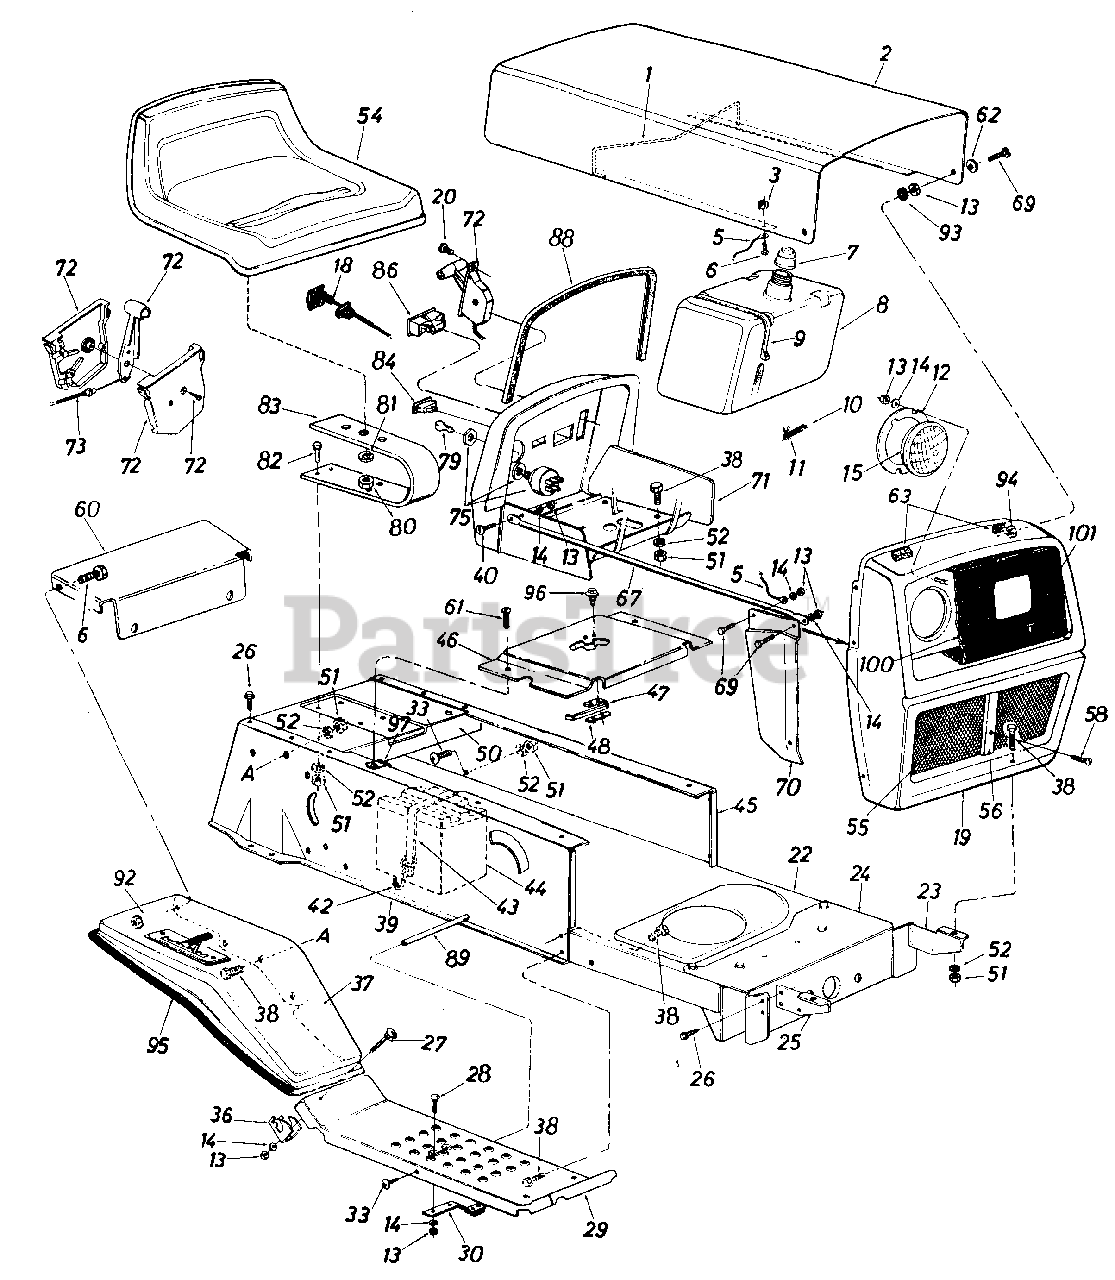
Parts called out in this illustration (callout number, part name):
3	Hex Sems Nut #10-24 Thd.
5	Hood Stop 7" Lg.
6	Truss Hd. Scr. #10-24 x 1/2"
7	Fuel Cap Gauge
8	Fuel Tank
9	Tie Strap
10	Fuel Line
12	Headlight Retainer
13	Hex Nut 1/4-20 Thd.
14	L-Wash 1/4" I.D.
15	Headlight
18	Choke Control 29" Lg.
19	Grille Ass'y.
20	Truss Mach. AB-Tap Scr. #10 x .50" Lg.
22	Lower Frame
23	Grille Mount Brkt. L.H.
24	Front Pivot Brkt.
25	Grille Mount Brkt. R.H.
26	Hex Wash. Hd. AB-Tap Scr. 5/16 x .75" Lg.
27	Carriage Bolt 1/4-20 x 2.0"*
28	Carriage Bolt 1/4-20 x .62"
29	Running Board
30	Blade Brake Ass'y.
33	Truss Mach. Scr. 5/16-18 x .75" Lg.
36	Fender Clamp
37	Fender
39	R.H. Side Frame
40	Hex Bolt 1/4-20 x .62" Lg.
42	Battery Strap Hook
43	Battery Hold Down Strap
44	12-V Battery
45	L.H. Side Frame
46	Shift Cover
47	Reverse Safety Switch
48	Insulator Nut Piate
50	Hitch Plate
51	Hex Nut 5/16-18 Thd.
52	L-Wash. 5/16 I.D.
54	Seat Ass'y.
56	Moulding
58	Hex Wash. F-Tap Scr. #8 x .38" Lg.
62	Fl-Wash 281 I.D. x .73 O.D.
63	Foam Strip 3/8 x 1-1/8 x 11/2
67	Grille Support Rod
69	Truss Hd. Scr. 1/4-20 x .75"
70	R.H. Grille Side Panel
71	Dash Panel Ass'y.
72	Throttle Control Box Ass'y.
73	Throttle Control Wire
75	Ignition Switch
79	Ignition Key
80	Hex N ut 1/2-13 Thd .
81	L-Wash. 1/2" I.D.
82	Hex Bolt 5/16-18 x 1.0"
83	Seat Spring 5.5" High
84	Light Switch
86	Ammeter
88	Molding Strip 27" Lg.
89	Running Board Rod
92	Hex Sems Nut #10-24 Thd.
93	Rubber Wash. 1/2" I.D. x 1.0 0 O.D. x .25"
94	Hex Sems Ins. L-Nut 1/4-20 0 Thd.
95	Trim Strip
96	Hex Wash. Hd. AB-Tap Scr. #8 x .50" Lg.
97	Speed Nut #10Z
101	Truss Scr. #10-24 x .62" Lg.
